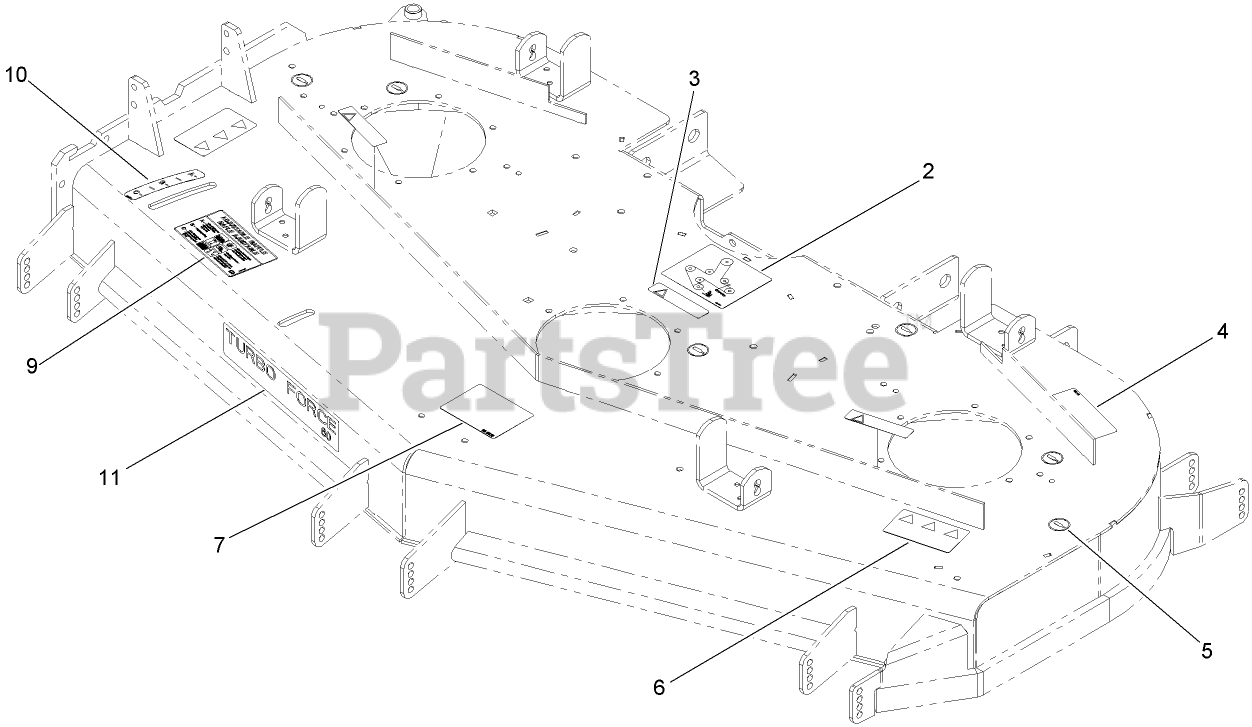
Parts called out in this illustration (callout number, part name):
2	DECAL-ROUTING, BELT
3	DECAL-WARNING
4	DECAL-TORQUE, BLADE BOLT
5	DECAL-GREASE
6	DECAL-DANGER
7	DECAL-ANTI SCALP
9	DECAL-ADJUSTMENT, BAFFLE
10	DECAL-SETTING, BAFFLE
